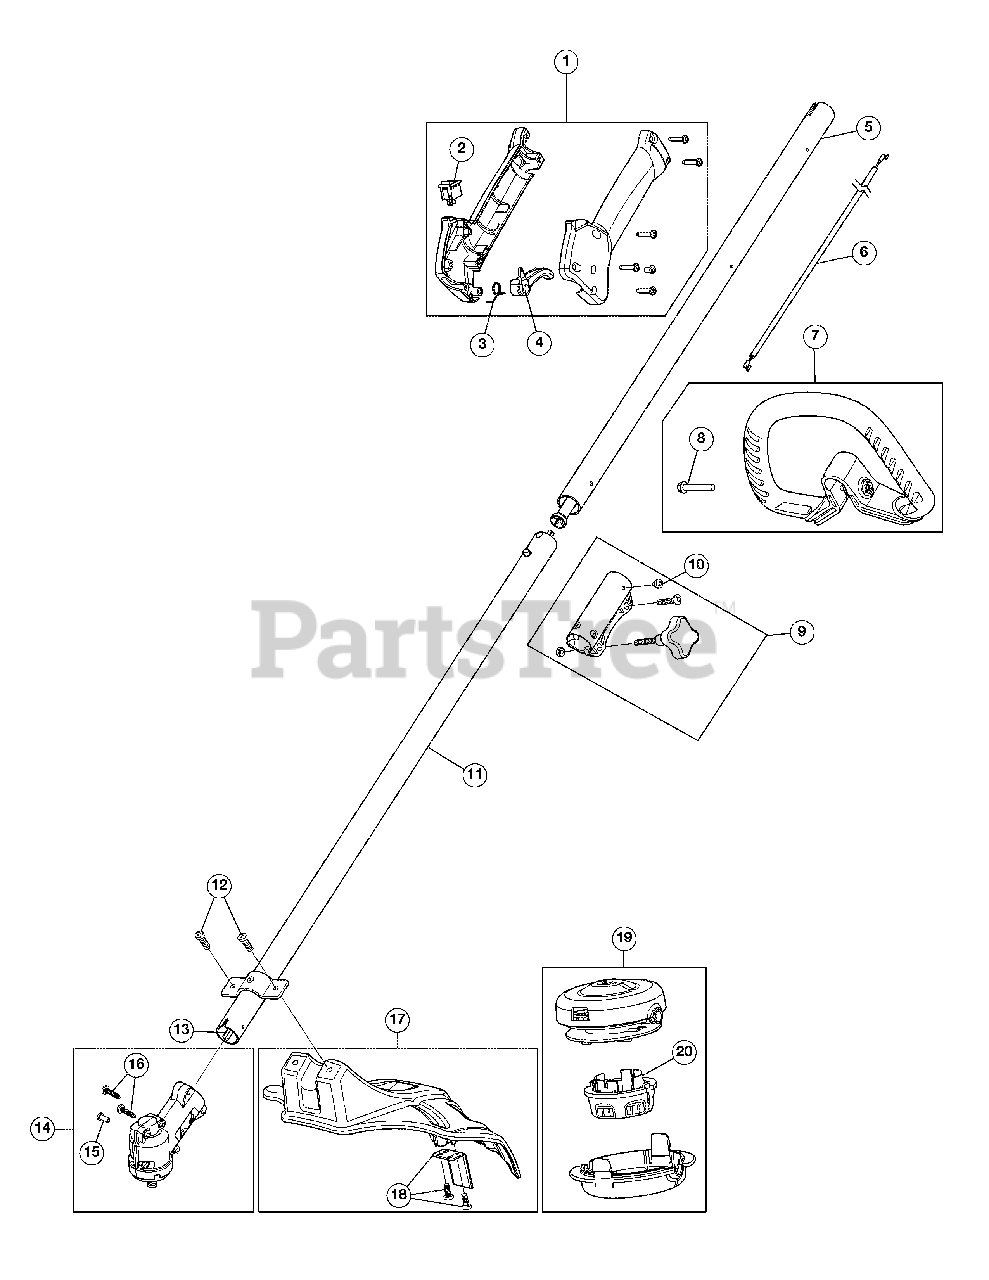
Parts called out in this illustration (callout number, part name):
1	Throttle Housing Assembly (Incl. 2 - 4)
2	Tigger Switch Assembly
3	Throttle Trigger Spring
4	Throttle Trigger
5	Upper Drive Shaft Housing Assembly
6	Throttle Cable Assembly
7	D-Handle Assembly (Incl. 8)
9	Split Boom Coupler (Incl. 10)
10	Coupler Anti-Rotation Screw
11	Lower Drive Shaft Housing Assembly
12	Shield Mounting Screws
13	Lower Flexible Drive Shaft
14	Gear Box Assembly (Incl. 15 and 16)
15	Anti-Rotation Screw
16	Gearbox Mounting Hardware
17	Shield Assembly (Incl. 18)
18	Blade Assembly
19	Cutting Head Assembly (Incl. 20)
20	Bump Knob
